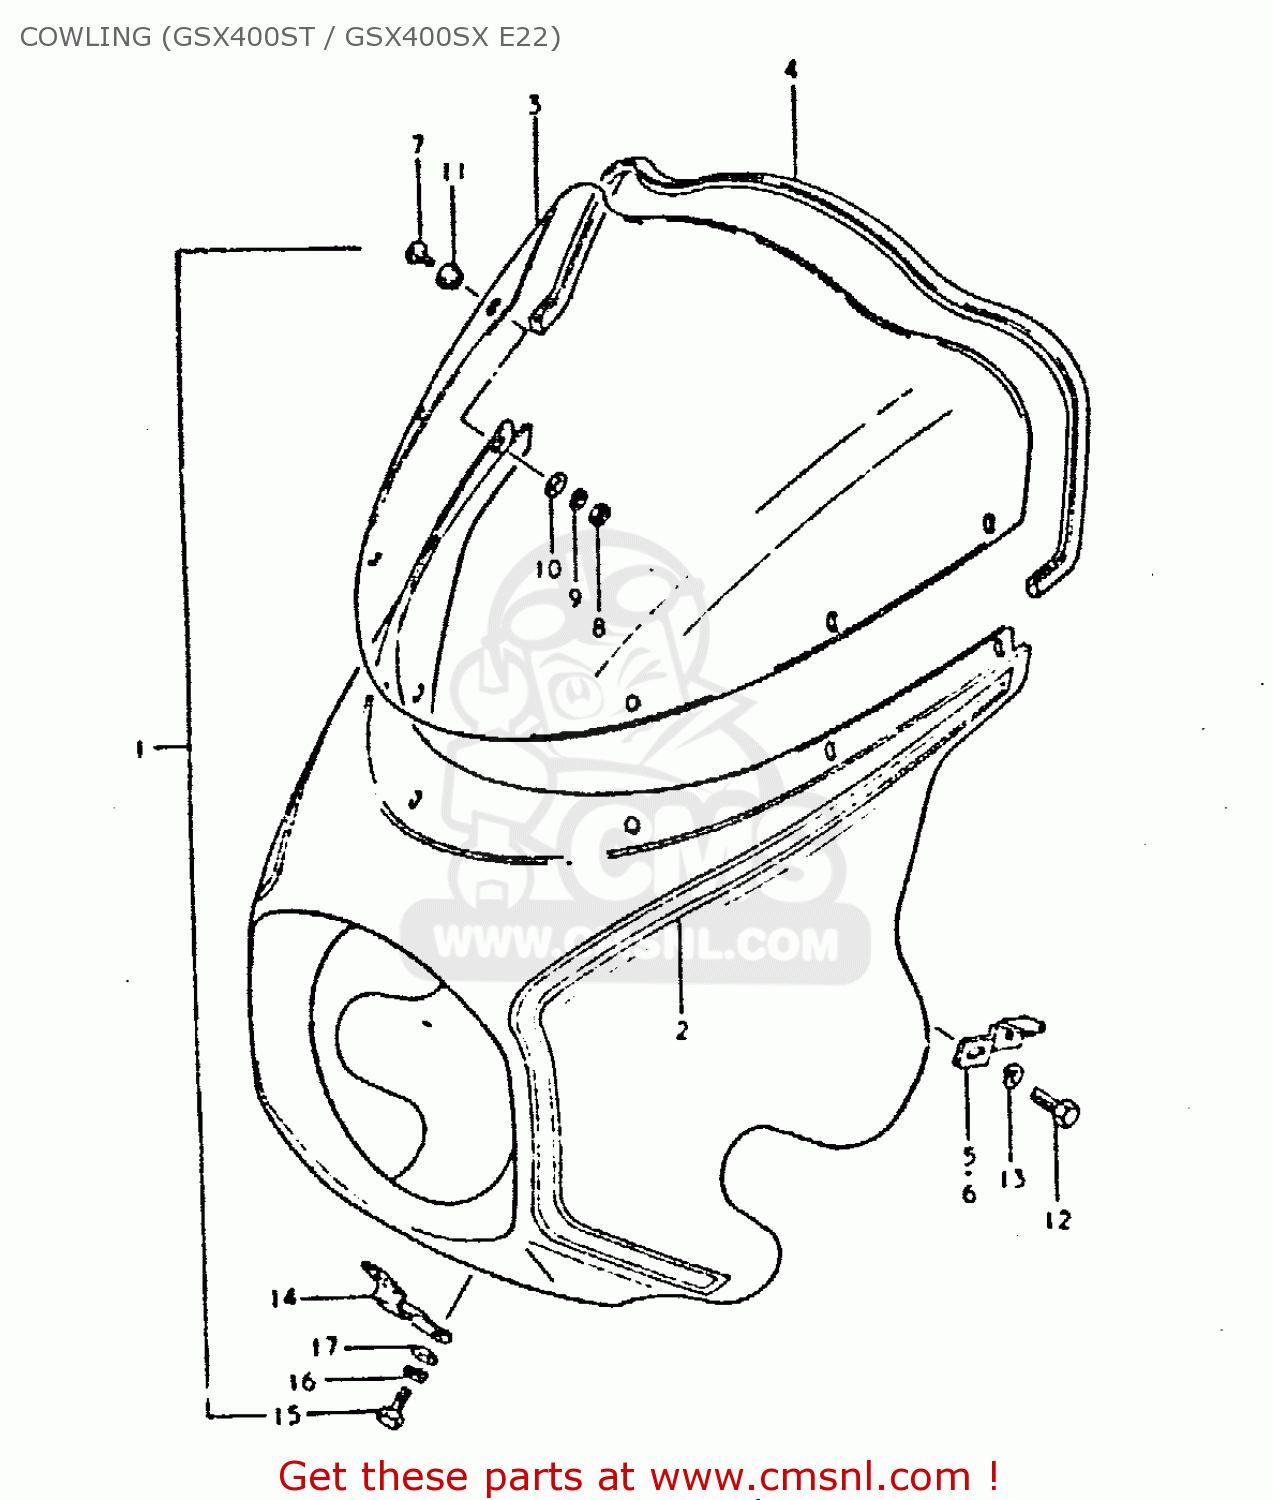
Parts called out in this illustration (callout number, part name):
1	COWLING ASSY
2	TAPE SET
3	WINDOW, COWLING
4	MOLD,COWLING
5	BRACKET,COWLING,RIGHT
6	BRACKET, LH
7	SCREW M5X12 DIN 7985/N
8	NUT
9	LOCK WASHER
10	WASHER
11	CUSHION
12	BOLT
13	LOCK WASHER
14	BRACKET,COWLING,LOWER
15	BOLT
16	LOCK WASHER
17	WASHER
